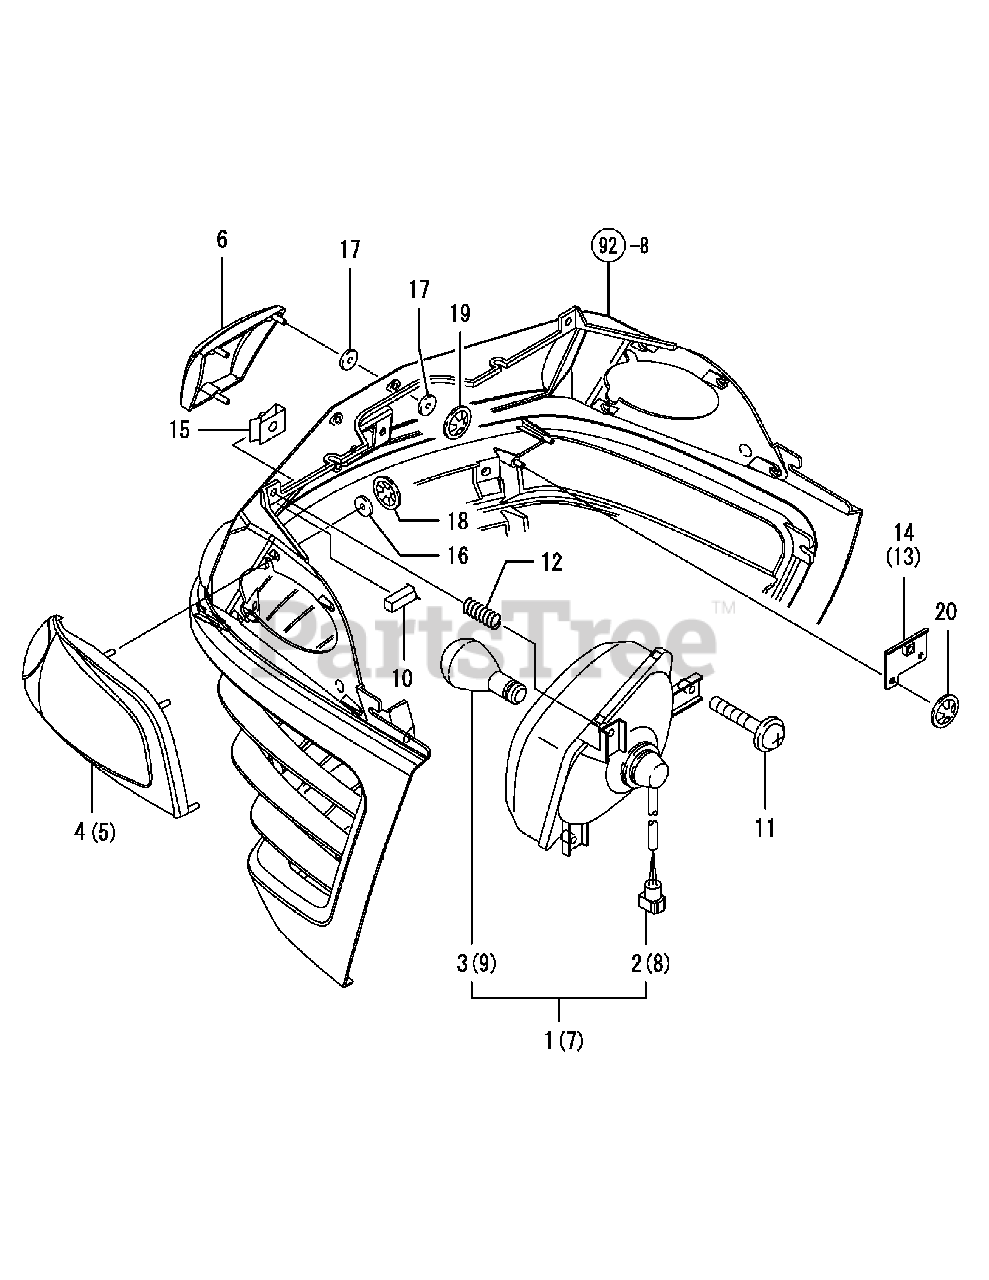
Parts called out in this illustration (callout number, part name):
1	HEADLIGHT ASSY, L.H.
2	WIRE ASSY, LEAD
3	BULB 12V45/45W
4	LENS, SIDE L.H
5	LENS, SIDE R.H
6	LENS, CENTER
6	Center Logo Label
7	HEADLIGHT ASSY, R.H.
8	WIRE ASSY, LEAD
9	BULB 12V45/45W
10	SEAL, HEADLIGHT
12	SPRING, ADJUST
13	BRACKET ASSY, L
14	BRACKET ASSY, R
18	NUT M5,SPEED
19	NUT M5,SPEED
20	NUT M5,SPEED
